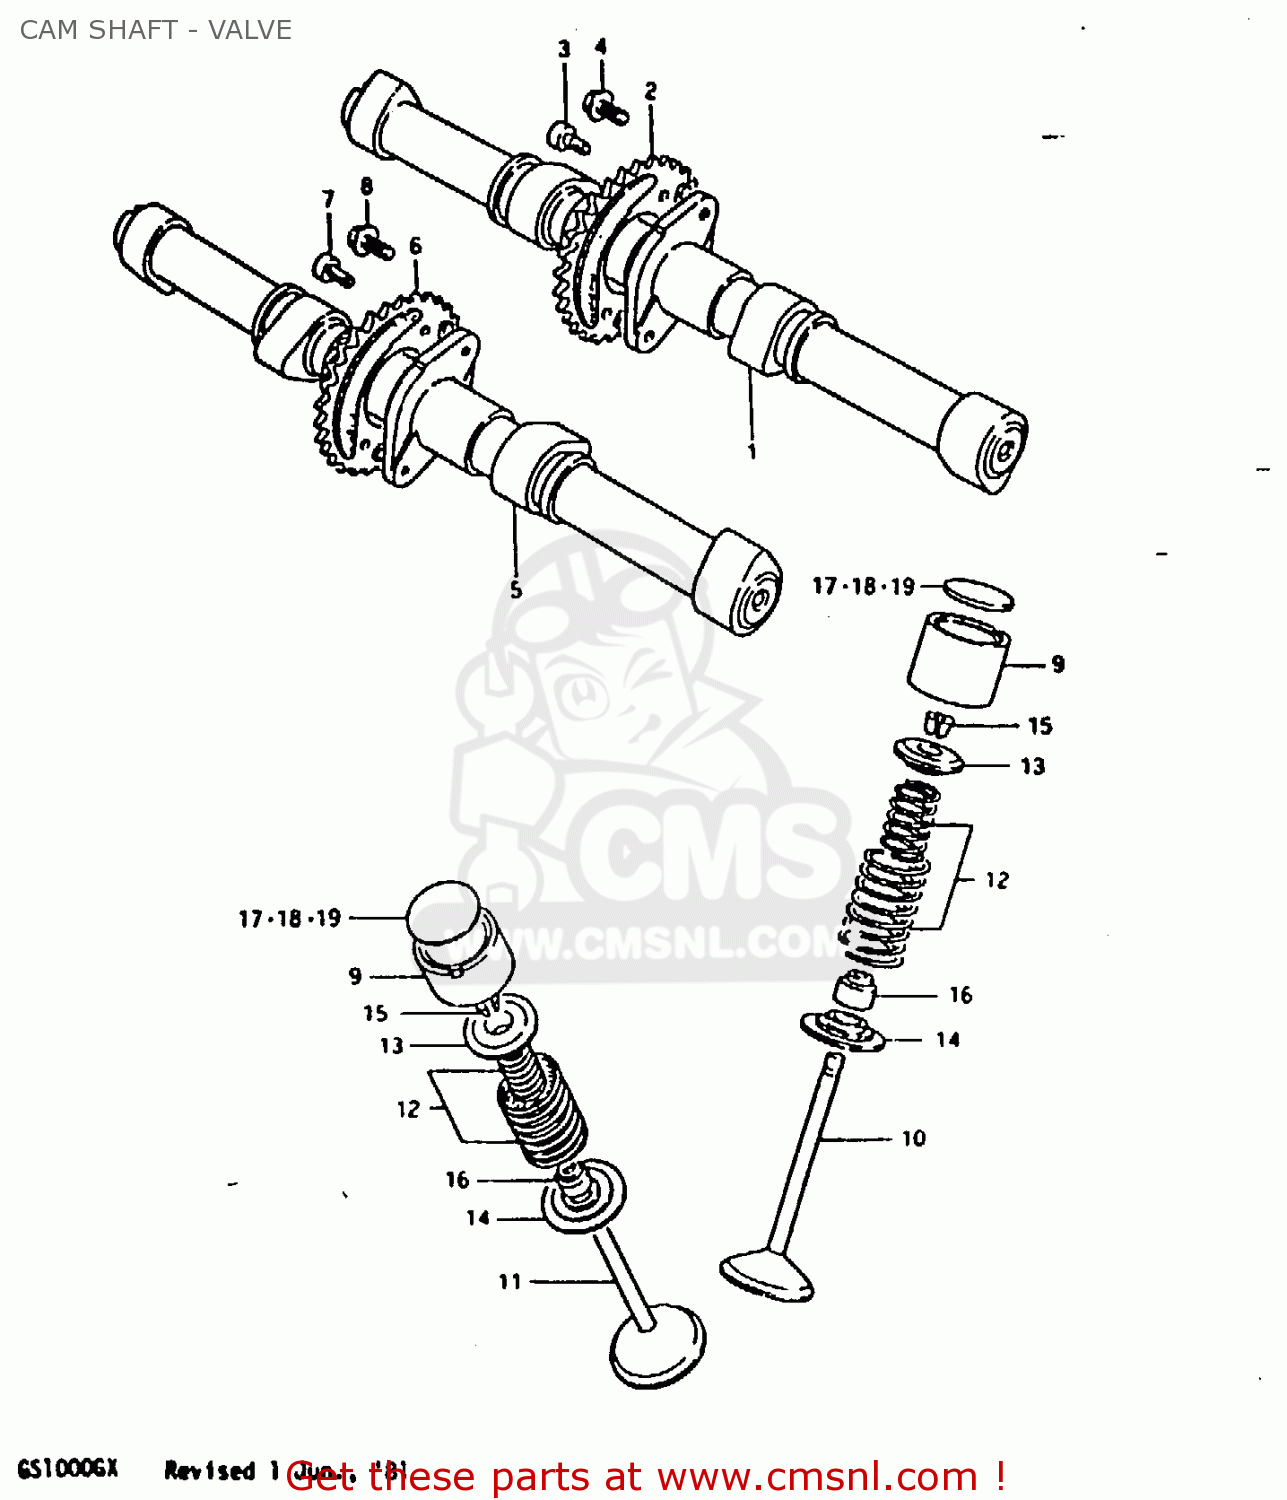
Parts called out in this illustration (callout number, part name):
1	CAMSHAFT
2	SPROCKET,INTAKE CAMSHAFT
3	BOLT 6X11
4	BOLT(7X11)
5	CAMSHAFT,EXHAUST
6	SPROCKET,EXHAUST CAMSHAFT
7	BOLT 6X11
8	BOLT(7X11)
9	TAPPET
10	VALVE,INTAKE
11	VALVE,EXHAUST
12	SPRING SET,VALVE
13	RETAINER,VALVE SPRING
14	SEAT,VALVE SPRING
15	COTTER VALVE
16	SEAL,OIL(7X14.4X9)
17	SHIM,TAPPET
18	SHIM,TAPPET
19	SHIM,TAPPET
